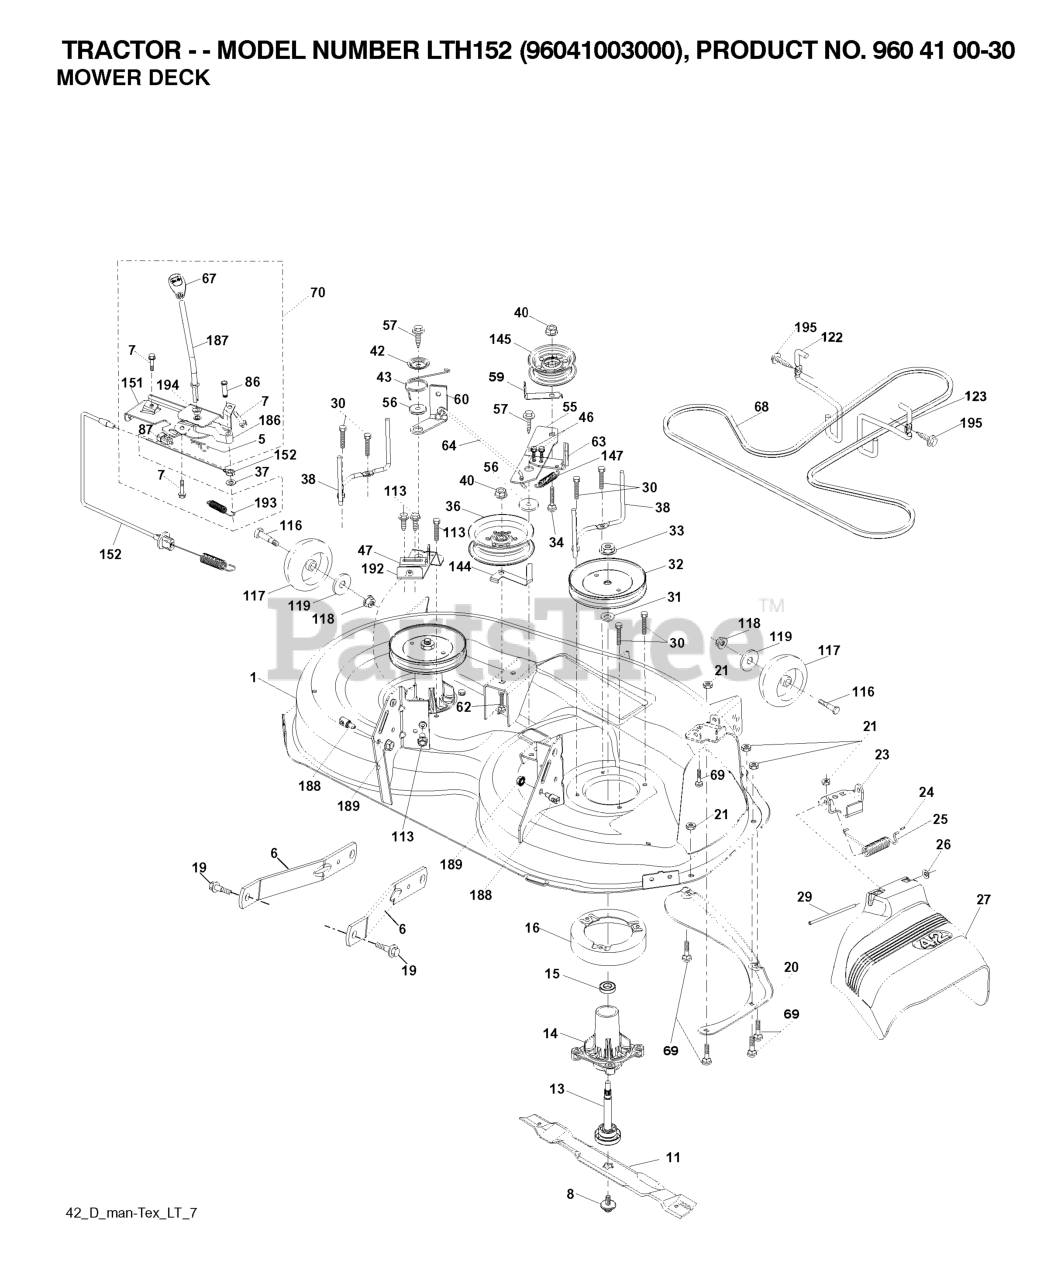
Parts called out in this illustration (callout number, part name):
5	RETAINER-SPRNG RB
6	ARM.SUSPENSION.MOWER.R
7	SCREW
8	BOLT.WASHER.ASM.7/16-2
11	42" HI-LIFT BLADE
13	SHAFT.ASM.MDRL.N/GREASE.38
14	RP.HOUSING.MANDREL.4PT.
16	STRIPPER.MANDREL.ROUND.BLACK
19	BOLT.SHOULDER
20	BAFFLE.VORTEX
21	LOCKNUT
23	BRKT.DEFLECTOR.38"2005+
24	CAP-SLEEVE LT
25	SPRING.TORSION.DEFLECT
26	NUT PUSH M
27	SHIELD.DEFLECTOR.MOWER.42"BLAC
29	ROD.HINGE
30	SCREW, WASHER HEAD
31	WASHER.SPACER.MANDREL
32	PULLEY.MANDREL.5.438.PD
33	NUT.FLANGE.LOCK.TOP
34	BOLT.3/8-16X1.50
36	PULLEY.IDLER.2006
37	WASHER
38	KEEPER.BELT.LH.MANDREL
40	NUT LOCK FLG 3/8-16 UNC
42	SPRING.TORSION.BRAKE
43	SRPING.TORSION.RETAINE
46	SCREW.1/4-20X5/8
47	BRKT.CLUTCH.CABLE
56	SPACER.RETAINER
57	SCREW 3/8-16X1
59	GUARD, BELT
60	ARM BRAKE MOWER
63	ARM BRAKE MOWER
64	LINK BRAKE
67	HANDLE.CLUTCH.CABLE.LT
68	BELT.DRIVE.MOWER.TEX.42"
69	BOLT
70	CLUTCH.ASM.MANUAL.LT.PRED
86	PIN ATTACHMENT CABLE
87	SWITCH.INTRLCK.CLUTCH.
113	BOLT.5/16HEX.WHS.HD
116	BOLT M
117	WHEEL.GAGE.HALF.SPOKED
118	LOCKNUT
119	WASHER.5/16.FLAT.STE.STD.
122	KEEPER BELT ENGINE LH
123	KEEPER BELT RH
144	KEEPER.BELT.MOWER
145	PULLEY.IDLER.48"PRIMARY
147	RETURN SPRING
151	BRACKET.CLUTCH CBL.PRED LT
152	CLUTCH CABLE
186	ARM ACTUATOR
187	LEVER.CONTROL.CL.CABLE.PRED LT
188	STUD.FASTNER.W/ANTI-ROTATE
189	NUT LOCK HEX FLANGE 5/16-18
192	BRKT.BRAKE.STAND.LH.
193	SPRING.PLUNGER.ACTUATOR
194	BEARING.CONTROL.LEVER.CLUTCH
195	SCREW, 3/8-16X3/4
